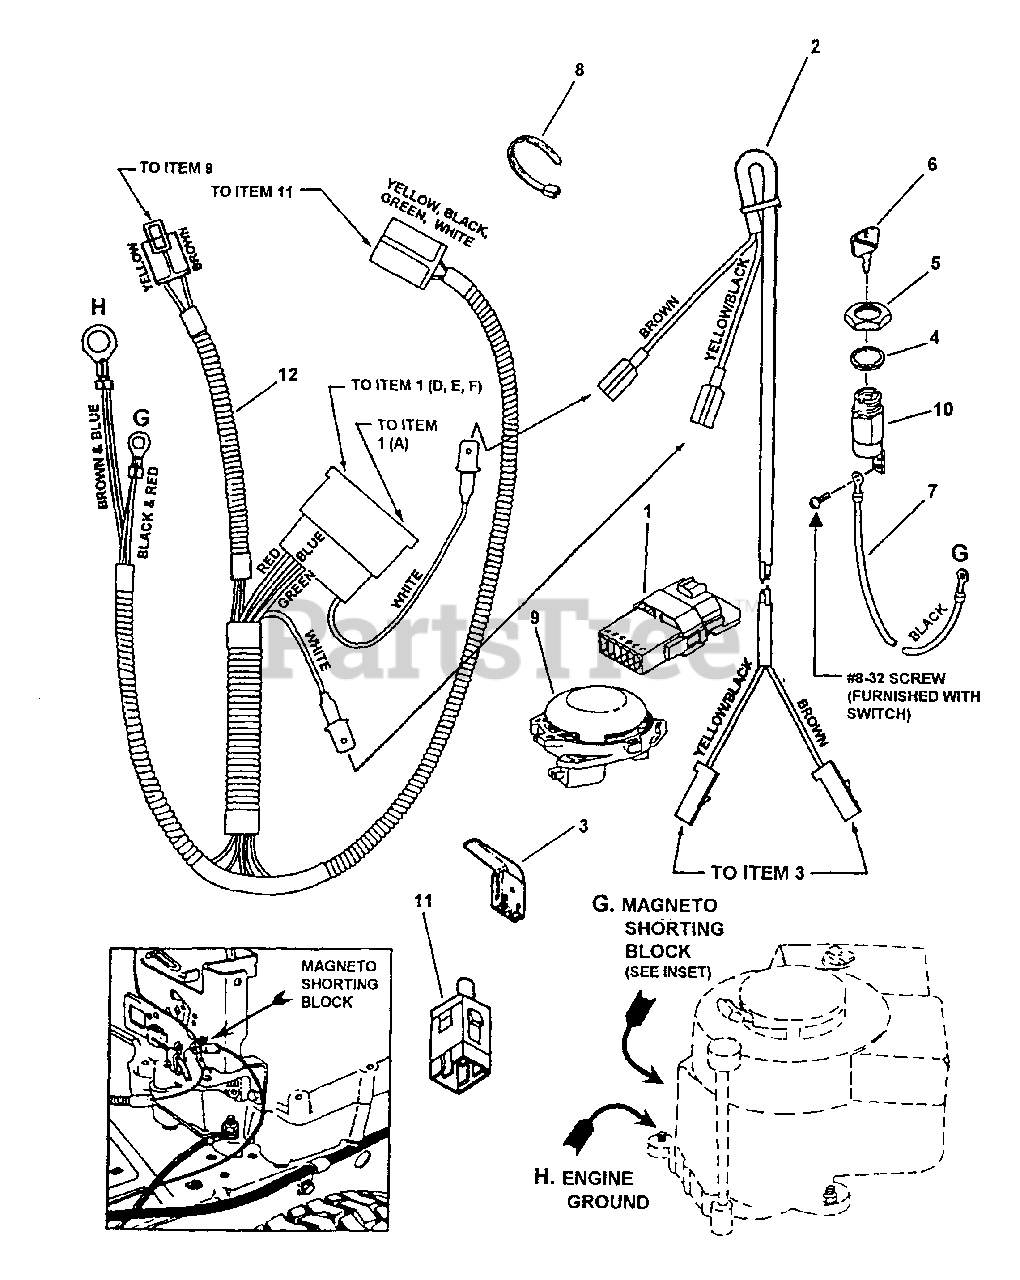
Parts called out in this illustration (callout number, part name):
1	INTERLOCK, Module
2	HARNESS, Deck Interlock
3	SWITCH, Deck Interlock (NO)
4	WASHER, 5/8 internal Tooth Lock
5	NUT, 5/8-32 Hex
6	KEY, Switch
7	WIRE, Ground (Recoil Start)
8	TIE, 7" Long Cable
9	SWITCH, Seat (NC)
10	SWITCH, (Recoil Start)
11	SWITCH, Traction Operator's Presence (NC/NO)
12	HARNESS, Operator's Presence Control
